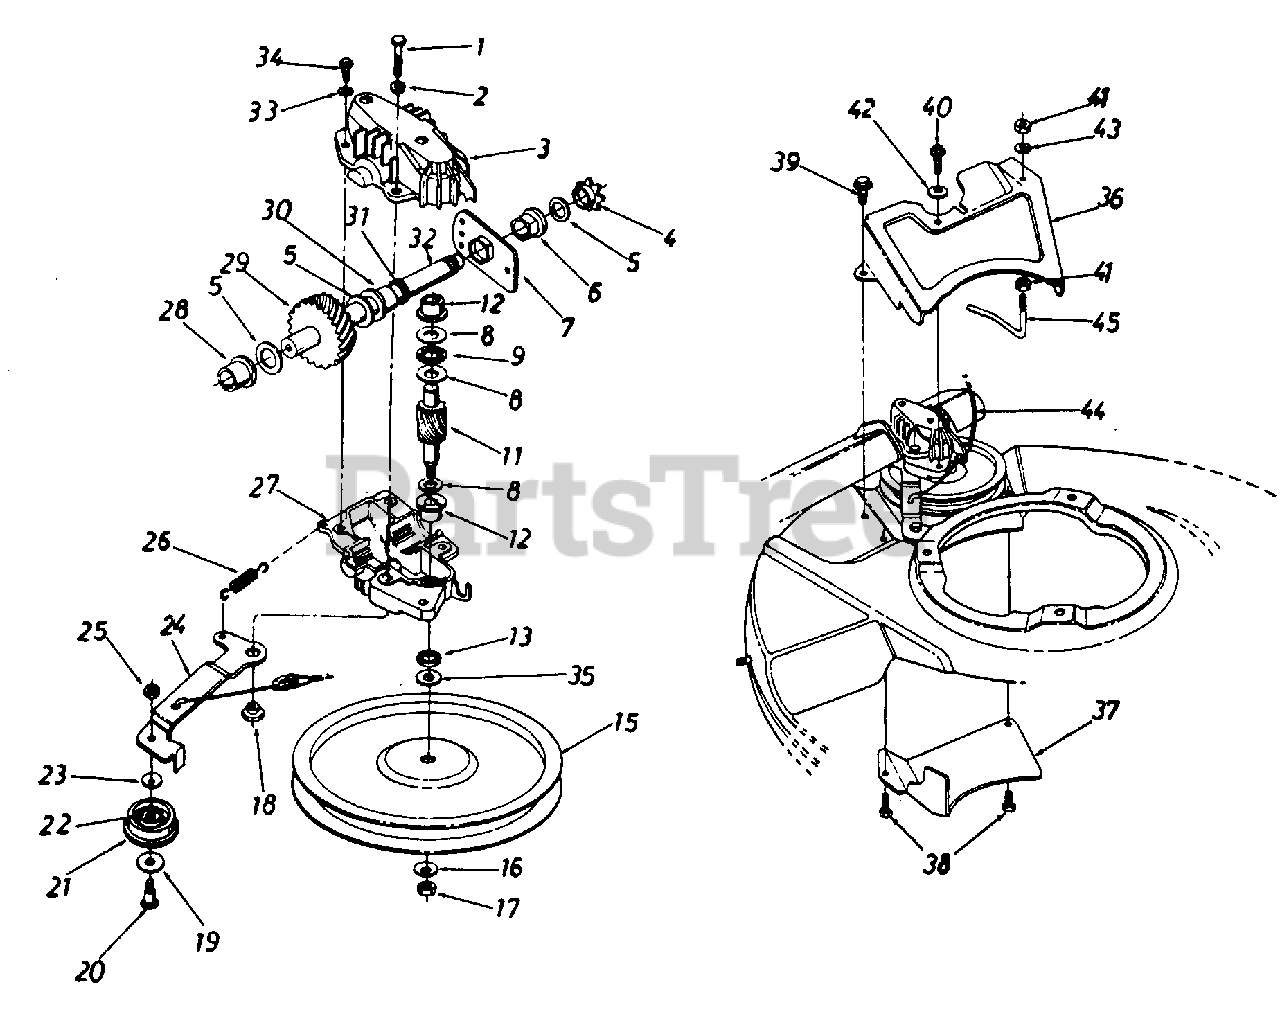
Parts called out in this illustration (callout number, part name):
1	SCREW-HEX
2	L-Wash. 1/4" I.D.
3	HOUSING HALF-UPPER
4	SPROCKET-7T
5	WASHER-FL
6	BEARING-HEX FLANGE
8	WASHER-THRUST.382 X .684
9	BEARING-THRUST
11	SHAFT-PINION 11 T
12	BEARING-FLANGE
13	SEAL-OIL-.375 ID
16	WASHER-SPRING BELL
17	NUT-LH THD-1/4 X 28
18	SPACER-SHLD
19	WASHER-FL .995 X .032
20	SCREW-SHLD
21	PULLEY
22	BEARING-NEEDLE
23	WASHER-SPRING BELL
24	BRACKET ASSY-IDLER
25	NUT-HEX 1/4-28
26	SPRING-EXTENSION
27	HOUSING HALF-LOWER
28	BEARING-FLANGE
29	SHAFT-ASSY W/GEAR
30	BEARING-FLANGE
32	SHAFT-ASSY W/GEAR
33	WASHER-LOCK-#10
34	SCREW-HEX WASH HD TAP
35	WASHER-HEX
39	SCREW-HEX WASH SF TAPP
40	SCREW-HEX B-TAP 1/4-.62
41	NUT-HEX 1/4-20
42	WASHER-SPRING BELL
43	LOCK WASHER 1/4 DIA
44	CABLE-CLUTCH
45	GUARD-BELT
